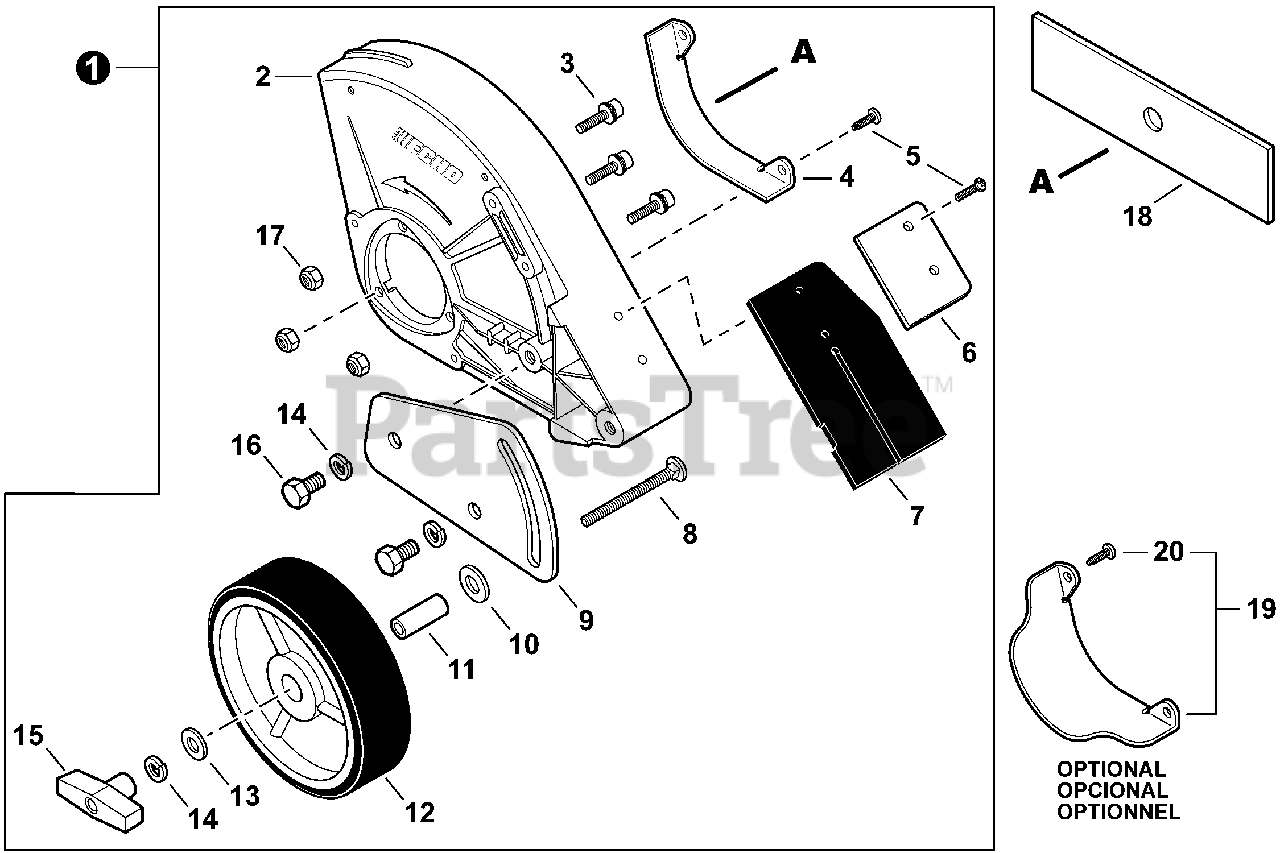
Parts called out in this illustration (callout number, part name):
1	SHIELD KIT, EDGER
2	SHIELD, BLADE
3	BOLT 5×25
4	GUARD, SHIELD
5	SCREW 4×12
6	PLATE, FLAP
7	FLAP, DEBRIS
8	BOLT 5/16×18×2 1/2
9	BRACKET, WHEEL
10	WASHER 10
11	COLLAR 12
12	WHEEL
13	WASHER 8
14	WASHER, SPRING 8
15	KNOB, FASTENER
16	BOLT 8×14
17	NUT, LOCK M5
18	BLADE, CUTTER - 2 PK
19	GUARD KIT, SHIELD
20	SCREW 4×12
